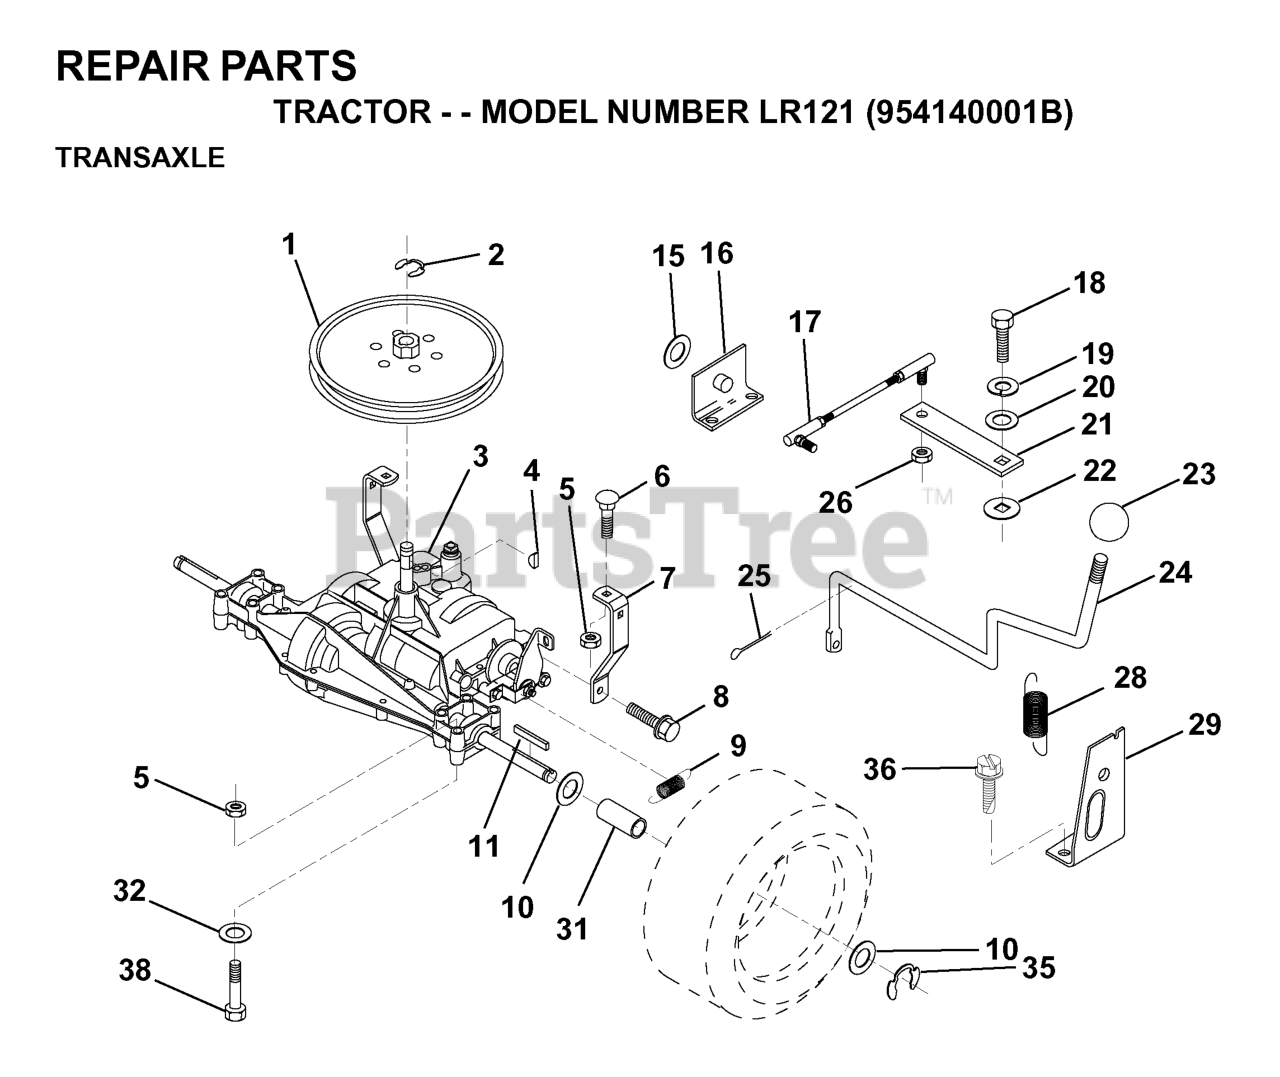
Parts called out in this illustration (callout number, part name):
2	RETAINING RING LT
4	KEY STD (1373) DANA
5	LOCKNUT
6	RP BOLT 5/16-18 X3/4 ZN/YEL GR
7	STRAP,TORQUE
8	SCREW.THDROL.5/16-18X3/4.TTY
9	SPRING,BRAKE RETURN
11	SQUARE KEY
15	WASHER
16	SUPT, HDLE SHT LH
18	BOLT 1/4-28X3/4
19	LOCKWASHER
22	WASH-SHFT PLT LT
23	KNOB T (1/2-HOLE)
24	ROD, SHIFT
25	PIN COTTER
26	LOCKNUT
28	SPRING.EXTENSION
29	SUPPORT HANDLE SHAFT RH
31	SPACER AXLE
32	WASHER
36	SCREW
38	BOLT HEX 5/16-18 GR 5
